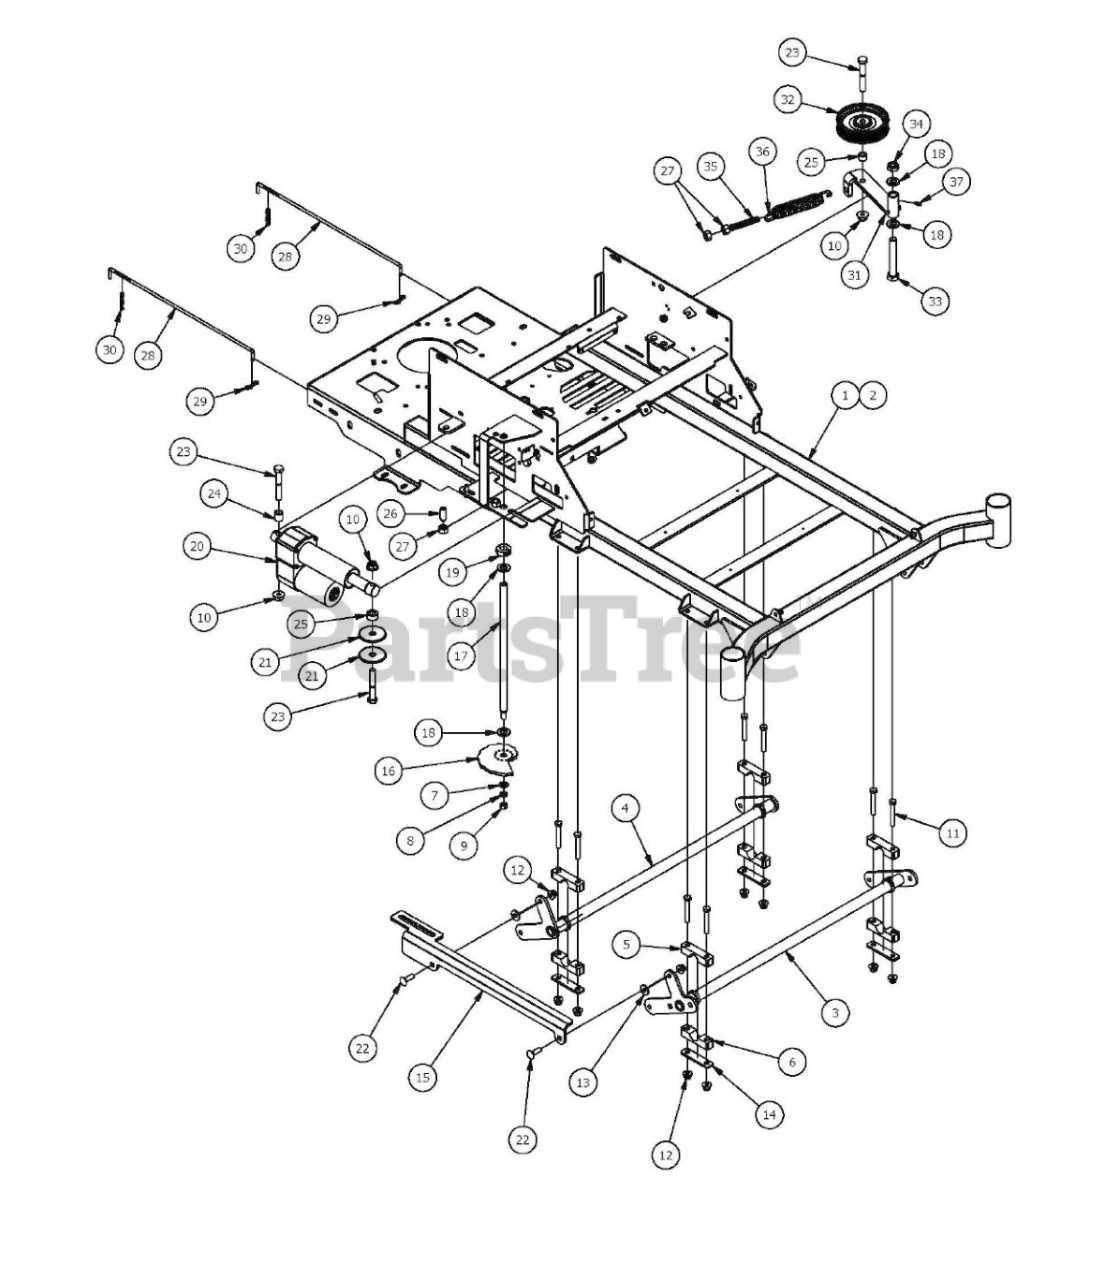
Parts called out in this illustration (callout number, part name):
1	2017 MZ/ZT 42"-48" Frame
2	ZT 54" and 60" Frame
3	Actuator Bar Front- 2017 MZ/ZT
4	Actuator Bar Rear-2017 MZ/ZT
5	Pillow Block MZ female
6	Pillow Block MZ male
7	3/8" Flat Washer
8	3/8" Lock Washer
9	3/8" Fine Threaded Jam Nut
10	1/2-13 Nylon Insert Flange Nut
11	3/8 x 2 1/2 Hex Bolt
12	3/8 Nylock Flange Nut
13	.360 ID Plastic Washer
14	Pillow Block Strap
15	2017 MZ/ZT Actuator Linkage
16	2017 MZ/ZT Cam Plate
17	2017 Deck Height Dial Rod ZT
18	.630 ID x1.22 OD x .142 THK Washer
19	5/8" Split Collar
21	Snubbing Washer
22	3/8" x 1 1/4" Carriage Bolt
23	1/2 x 2-3/4 Hex Bolt
24	Spacer 3/4 OD x 1/2 ID x 3\4 Length
25	1/2 Set Collar w/set Screw
26	Dial Rod Plunger
27	1/2" Hex Nut
28	Neutral Rod
30	Neutral Rod Clip
31	Pump Idler Bracket
32	4 3/4" Idler Pulley
33	5/8" x 4" Hex Bolt
34	5/8" Nylock (1/2 Jam)
35	All Thread-Pump Idler Tensioner
36	2015 Deck Idler Spring
37	1/4" Press In Grease Fitting
